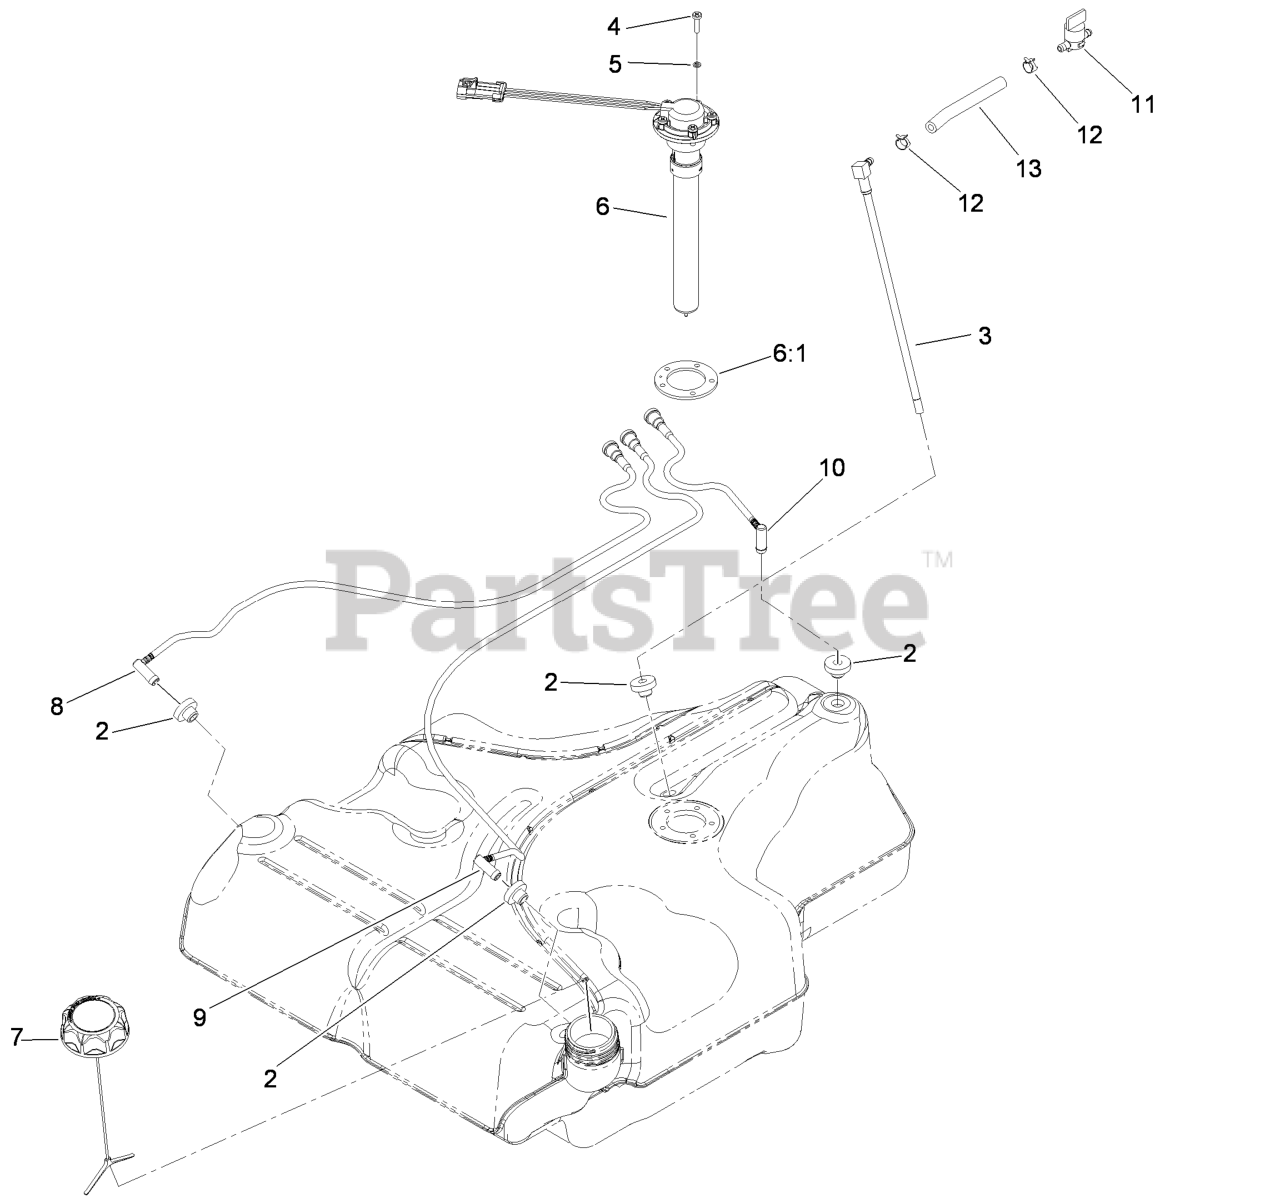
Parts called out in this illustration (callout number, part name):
2	BUSHING
3	FUEL LINE KIT (WITH GROMMET)
4	SCREW-PAN
5	WASHER-LOCK
6:1	GASKET-SENDER, FUEL
8	RH VENT LINE KIT (WITH GROMMET)
9	LH VENT LINE KIT (WITH GROMMET)
10	REAR VENT LINE KIT (WITH GROMMET)
11	VALVE-FUEL
12	CLAMP-HOSE
13	HOSE-FUEL
